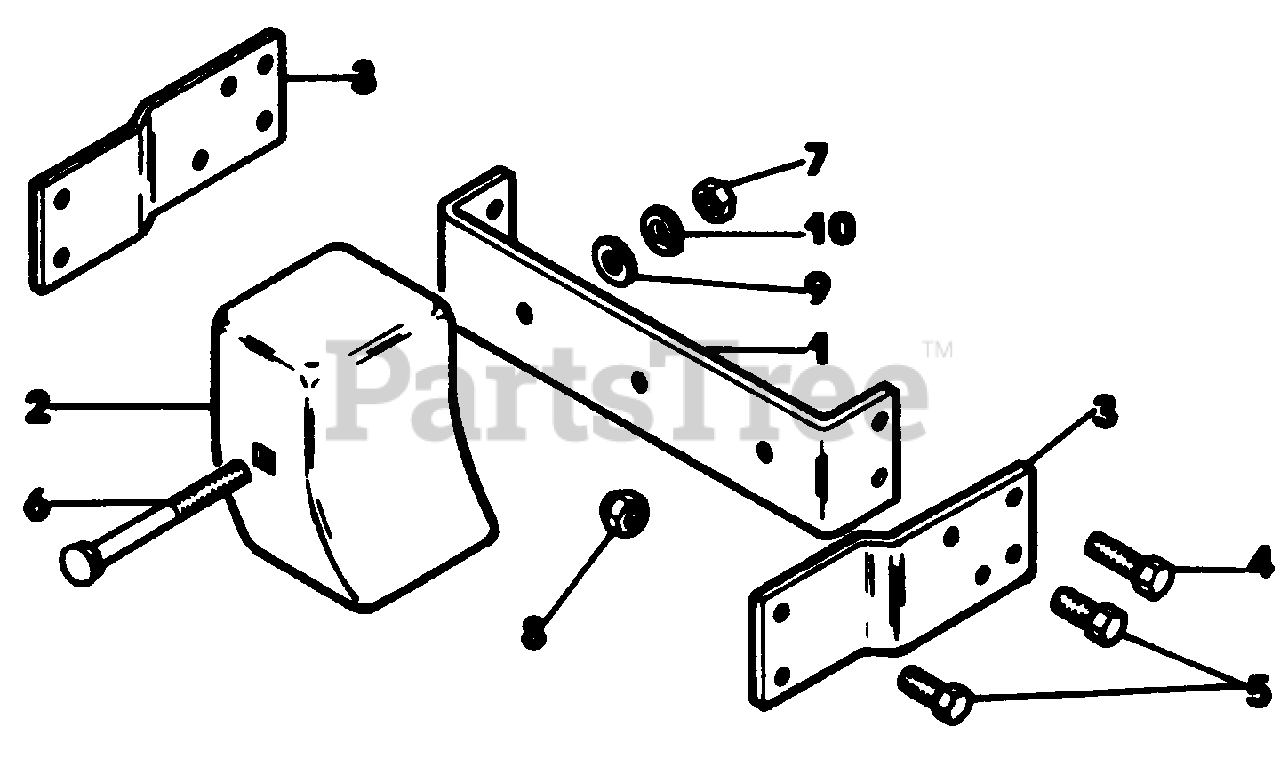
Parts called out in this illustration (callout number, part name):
1	Mounting Bracket
1	FOOT, right hand
2	Weight
2	FOOT, left hand
3	Thatcher Bracket
3	GUARD, FOOT POCKET, right hand
4	Cap Screw. Hex Hd. 3/8-16 x 1" Plated, Grade 5
4	GUARD, FOOT POCKET, left hand
5	Cap Screw, Hex Hd. 3/8-16 x 3/4 Plated, Grade 5
5	FRAME, FRONT PANEL
6	Bolt, Carriage 1/2-13 x 5-1/2 Plated
6	BRACE, FRONT PANEL FRAME
7	Nut, Hex 1/2-13 Plated
7	SUPPORT, CHUTE CONTROL CRANK
8	Nut, Hex Cone Lock 3/8-16 Plated
8	BRACKET, REAR ATTACHING, right hand
9	Washer Flat 1/2 Plated
9	BRACKET, REAR ATTACHING, left hand
10	Washer, Spring Lock 1/2 Plated
10	PLATE, REAR ATTACHING
11	CROSS BAR, REAR
12	POST, FRONT, right hand (straight w/screw)
13	POST, FRONT, left hand (straight w/screw)
14	BRACE, TOP, right hand
15	BRACE, TOP, left hand
16	TOP FRAME, HTS
17	POST, REAR CORNER, right hand
18	POST, REAR CORNER, left hand
19	"L" BRACKET
20	3/4" LOOP
21	FRONT PANEL VINYL
22	WINDSHIELD
23	DOOR, right hand
24	DOOR, left hand
25	REAR CURTAIN
26	TOP, FIBERGLASS, HTS (trim)
27	CRANK, CHUTE CONTROL
28	PARTS BAG (contents listed below)
29	1/4"-20 LOCKNUT
30	DOOR HINGE
31	1/4"-20 x 3/4" BOLT
32	SPRING, DOOR LATCH
33	1/4" FLAT WASHER
34	5/16"-18 x 1-1/2" BOLT
35	3/8"-16 LOCKNUT
36	3/8"-16 x 3/4" BOLT
